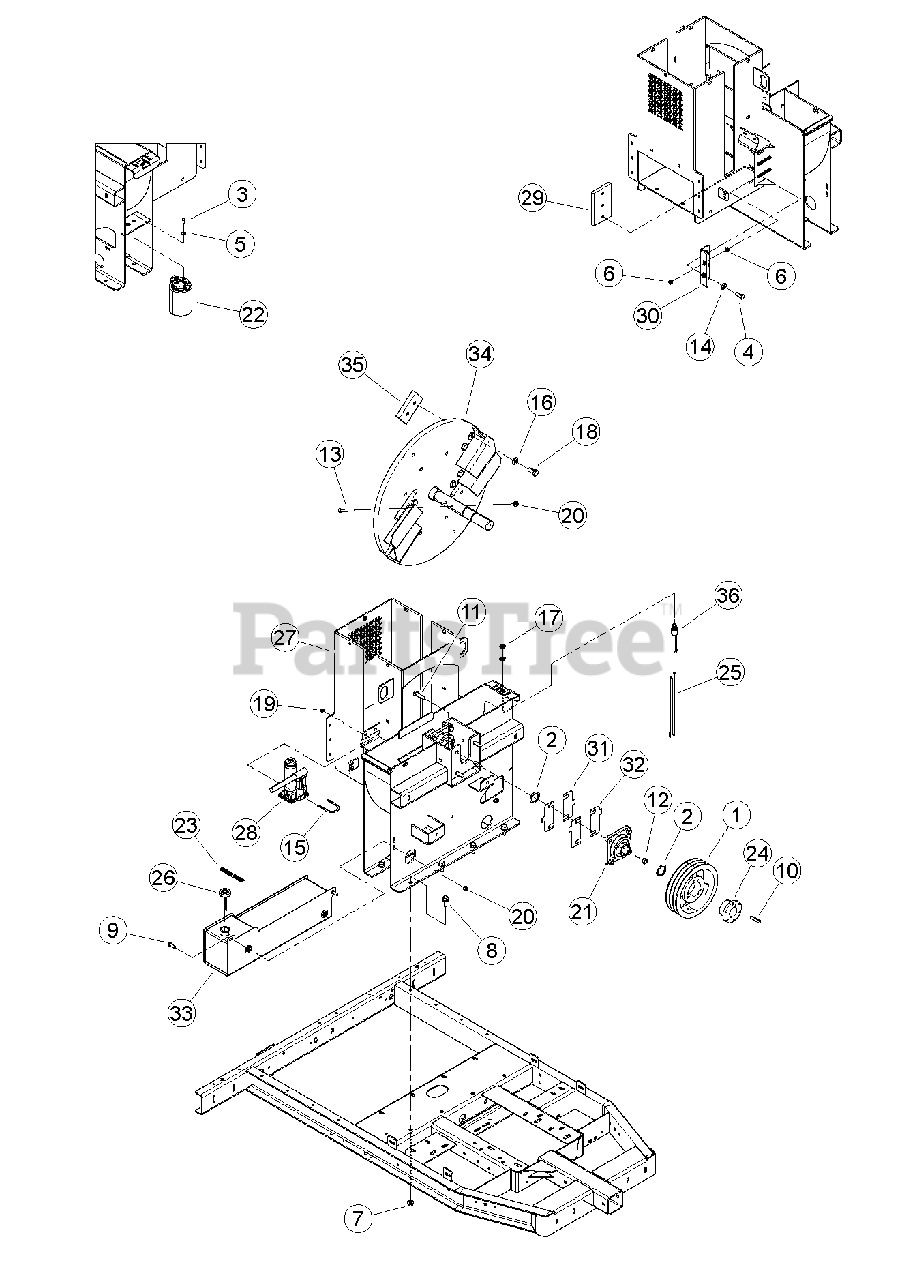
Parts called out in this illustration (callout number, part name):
1	SHEAVE, 3BQ9.4 SK
2	RING, 1-3/4 EXT HEAVY DUTY SNAP
3	BOLT, 1/4 X 3/4 GR5 HEX HD ZP
4	BOLT, 1/2 X 1-1/4" GR5 HHCS NC ZP
5	WASHER, 1/4" FLAT ZP
6	NUT, 3/8" SERRATED FLANGE NC ZP
7	NUT, 1/2-13 NYLOCK FLANGE
8	BOLT, 1/2 -13 X 1-1/4 FLANGE NC
9	BOLT, 3/8 X 1-1/4" GR5 CRG NC ZP
10	KEY, 3/8" SQ X 2" LG PLAIN
11	BOLT, 9/16 X 1-3/4 HEX GR5 ZP
12	NUT, 9/16 CENTER LOCK GRB ZP
13	BOLT, 3/8 X 3-1/2 FULL THD ZP GR5
14	WASHER, 1/2 HI-STRENGTH SAE ZP
15	U-BOLT, 1/4 X 1-1/2 PIPE
16	WASHER, 5/8 SAE HARDENED
17	NUT, 5/8-32 JAM
18	BOLT, M16 X 2.0 X 30 HEX HD W/PATCH
19	NUT, 1/4-20 NYLOCK-FLANGE
20	NUT, 3/8-16 NYLOCK FLANGE
21	BEARING, 1-3/4 4 BOLT FLANGE
22	ASSEMBLY, HYDRAULIC FILTER
23	DECAL, HYDRAULIC FLUID
24	BUSHING, SK 1-3/4"
25	WIRE ASSEMBLY, 37" FM SPADE AND RING
26	CAP, HYDRAULIC W/ DIPSTICK
27	WELDMENT, 6 IN CHIPPER HOUSING
28	JACK, HYDRAULIC 2 TON
29	ANVIL, 6" CHIPPER
30	WELDMENT, BLOCK ADJUSTOR
31	SHIM, 20 GA.
32	SHIM, 16 GA.
33	WELDMENT, HYDRAULIC TANK
34	WELDMENT, 6 CHIPPER ROTOR
35	KIT, CHIPPER BLADE
36	ASSEMBLY, SEALED SWITCH
